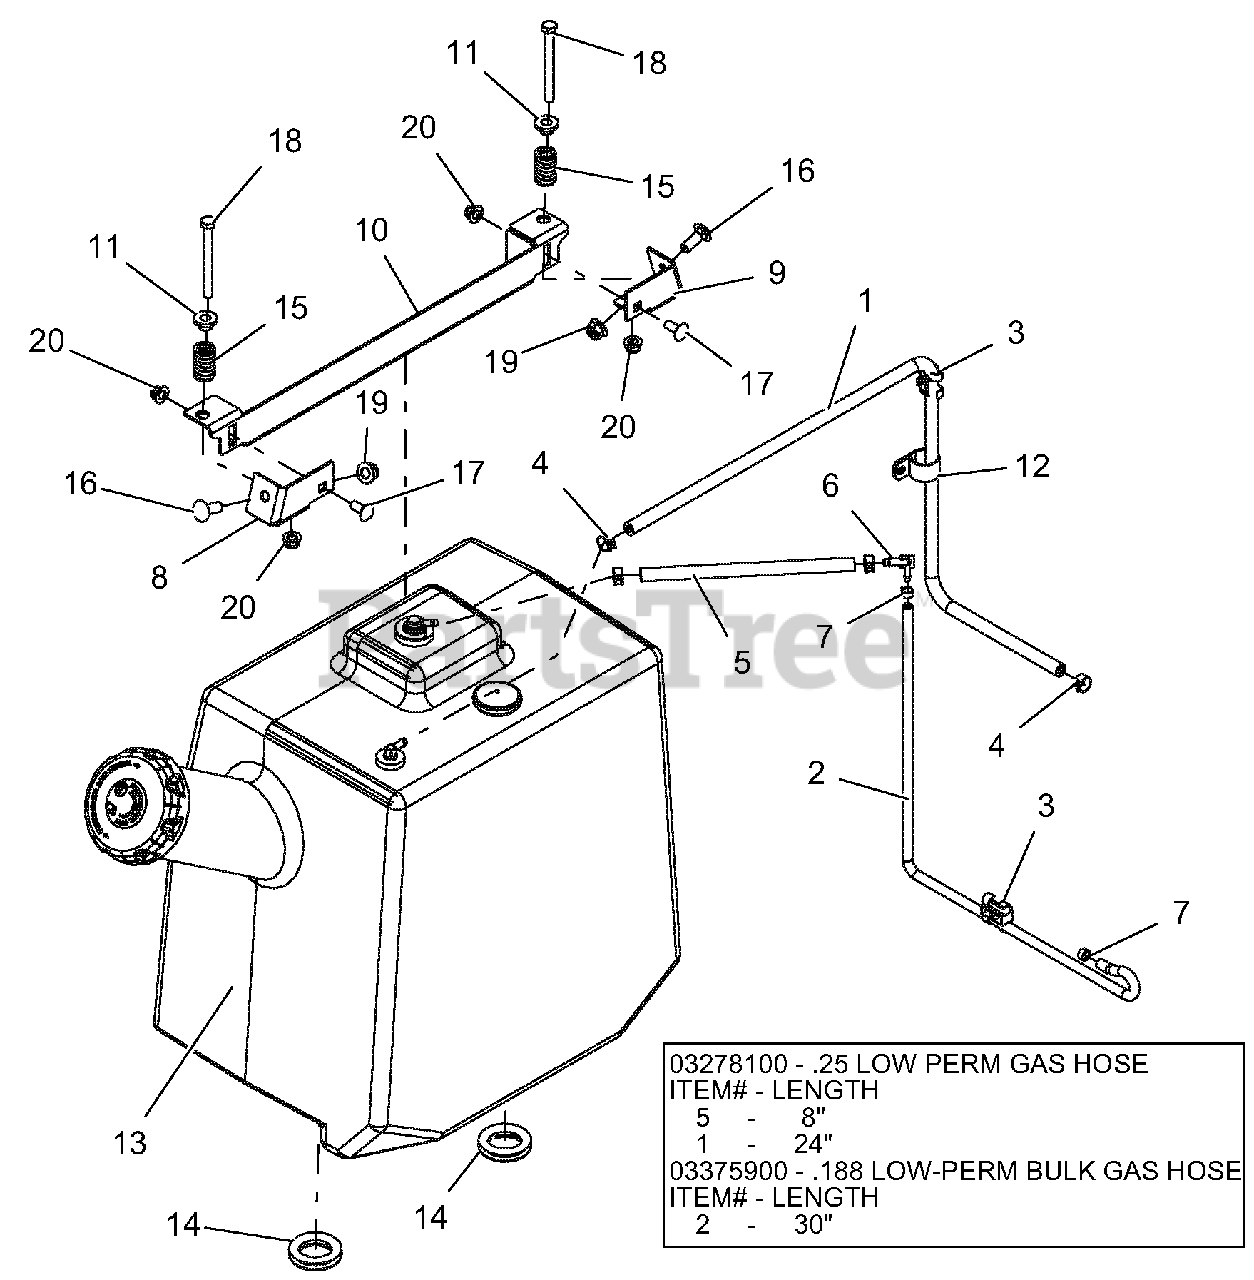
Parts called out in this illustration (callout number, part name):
1	.25 LOW PERM GAS HOSE
2	HOSE, .188 LOW-PERM BULK GAS
3	CLIP, T, .38-.50
4	CLAMP, FUEL LINE
5	.25 LOW PERM GAS HOSE
6	FITTING-3/16X1/4 90DEGREE VAC
7	CLAMP - HOSE, SPRING .188
8	WLDMT, TANK HOLDDOWN-RH
9	WLDMT, TANK HOLDDOWN-LH
10	HOLDDOWN, FUEL TANK
11	BSHG, FLG .385 X .500 X .875 X .406
12	CLAMP, CUSHIONED STEEL REV
13	ASSY, EPA PROSTANCE FUEL TANK
14	GROMMET, 1.25"
15	SPRG, COMPRESSION
16	BLT-RDHDSQNK .38-16X1.00 G5 YWZC
17	BLT-RDHDSQNK .31-18X.75 G5 YWZC
18	BLT-HEX .31-18X3.25 GR5 YWZC
19	NUT-LK-NYL-FLG .38-16 YWZC
20	NUT-LK-NYL-FLG .31-18 YWZC
